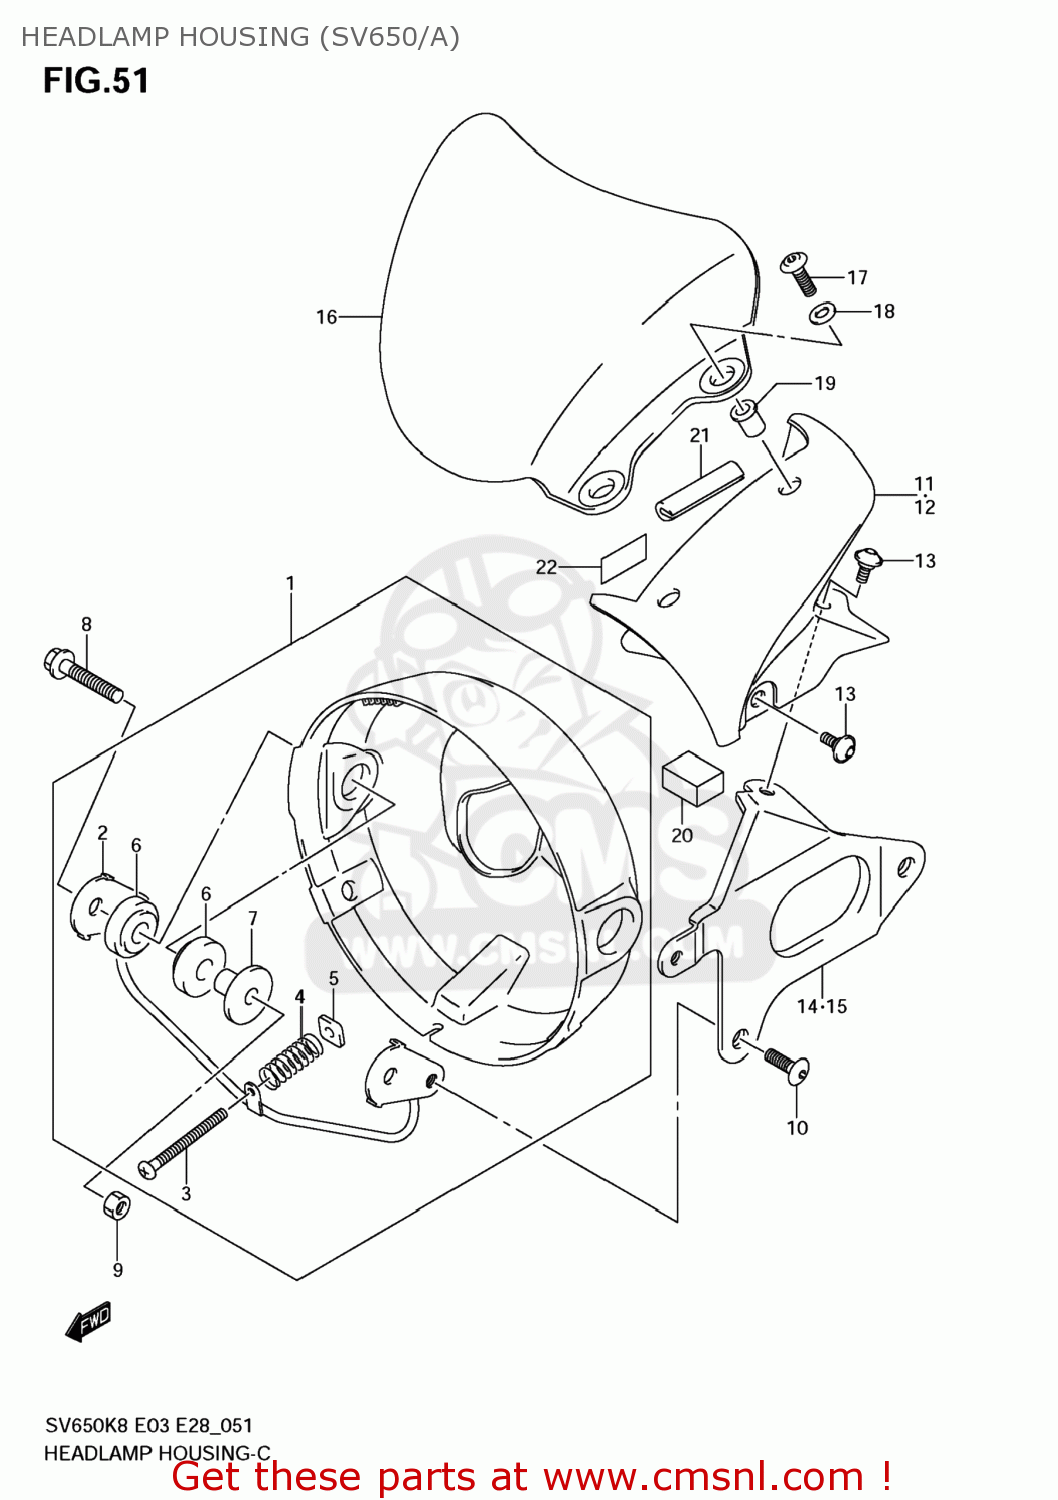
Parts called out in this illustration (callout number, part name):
1	HOUSING ASSY,HEADLAMP
2	PLATE,HEADLAMP
3	SCREW(5X45)
4	SPRING,HEADLAMP ADJUSTER
5	NUT,HEADLAMP ADJUSTER
6	CUSHION
7	SPACER(8.6X12X21.3)
8	BOLT(8X35)
9	NUT
10	SCREW(6X16)
11	COVER,HEADLAMP HSG,R
12	COVER,HEADLAMP HSG,L
13	SCREW(5X13)
14	PLATE,HOUSING COVER,R
15	PLATE,HOUSING COVER,L
16	COVER,METER
17	SCREW(5X18)
18	WASHER
19	NUT
20	CUSHION,FR PANEL LID
21	MOLDING
22	TAPE
